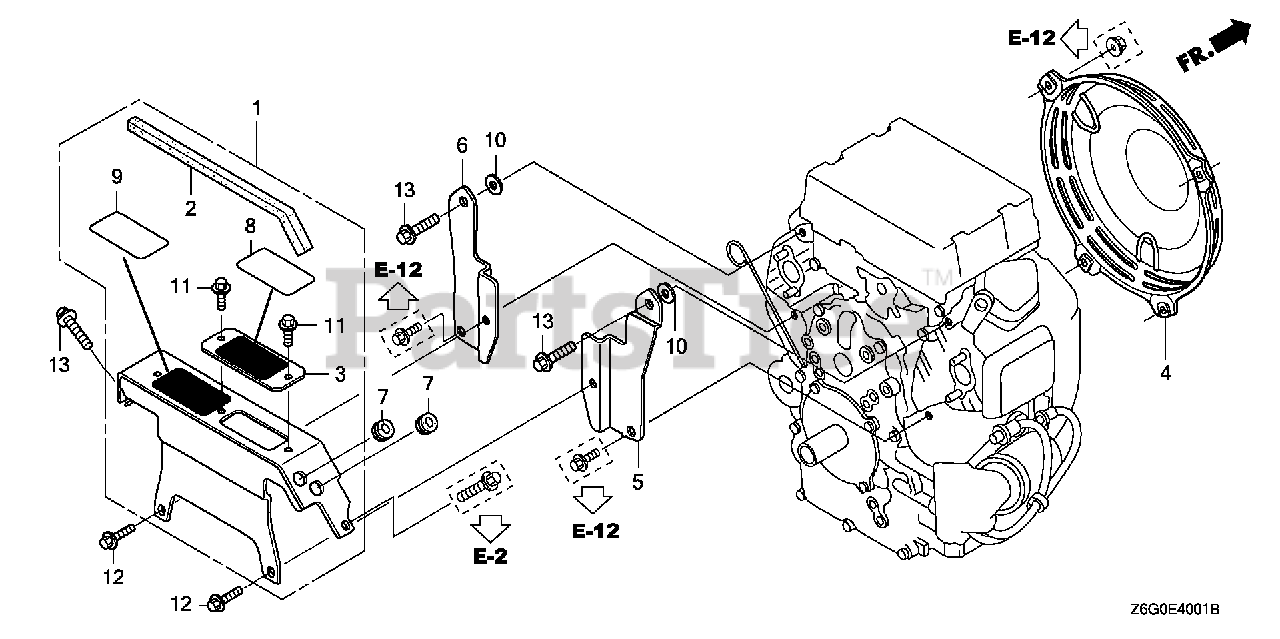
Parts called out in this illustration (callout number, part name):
1	COVER ASSY., CONTROL
2	SEAL, CONTROL COVER
3	COVER B, CONTROL
4	PROTECTOR, FAN COVER
5	BRACKET, R. SHROUD
6	BRACKET, L. SHROUD
7	RUBBER, SEAT LOCK BAR CUSHION
8	LABEL, OPERATOR NOTICE (E)
9	LABEL, OPERATOR NOTICE (F)
10	WASHER, PLAIN (8MM)
11	BOLT, FLANGE (6X12)
12	BOLT, FLANGE (6X16)
13	BOLT, FLANGE (8X20)
